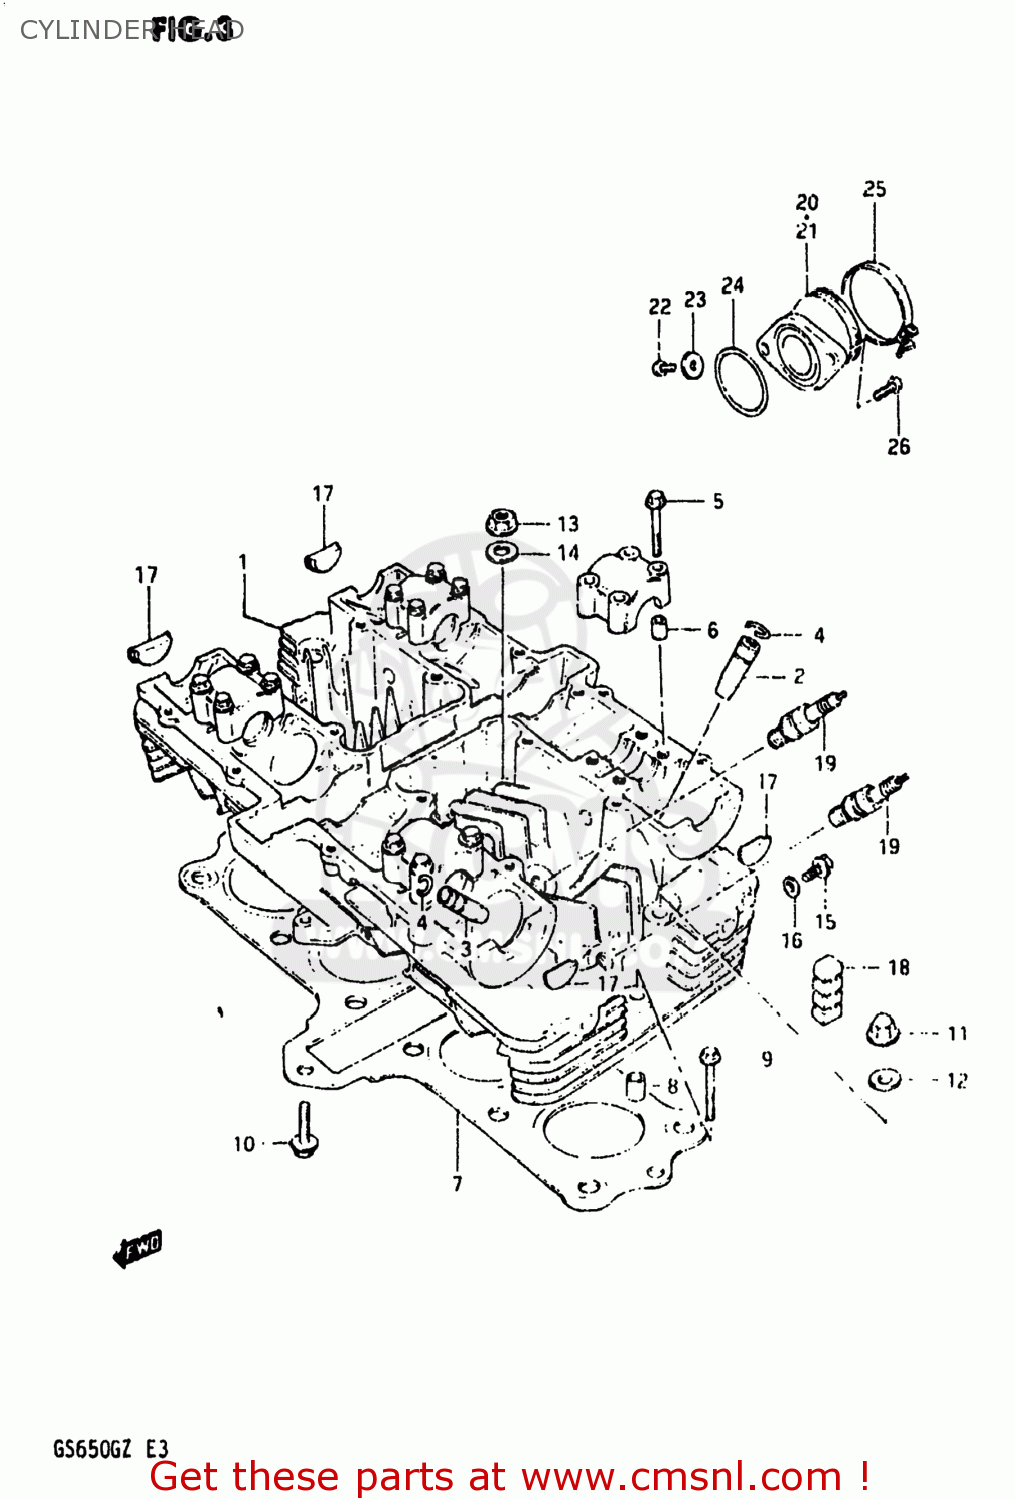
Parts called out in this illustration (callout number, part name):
1	HEAD,CYLINDER
2	GUIDE,INTAKE VALVE
3	GUIDE,EXHAUST VALVE
4	RING,SNAP
5	BOLT(6X39)
6	PIN(6.2X8X11)
7	GASKET,CYLINDER HEAD (MCA)
8	PIN
9	BOLT,UNDER
10	BOLT
11	NUT
12	GASKET (NAS)
13	NUT
14	WASHER(8.5X19X2.3)
15	BOLT
16	GASKET (NAS)
17	PLUG
18	PAD,CYLINDER
19	SPARK PLUG D8EA
20	PIPE,INTAKE,R
21	PIPE,INTAKE,L
22	BOLT
23	WASHER
24	O-RING
25	CLAMP
26	SCREW
